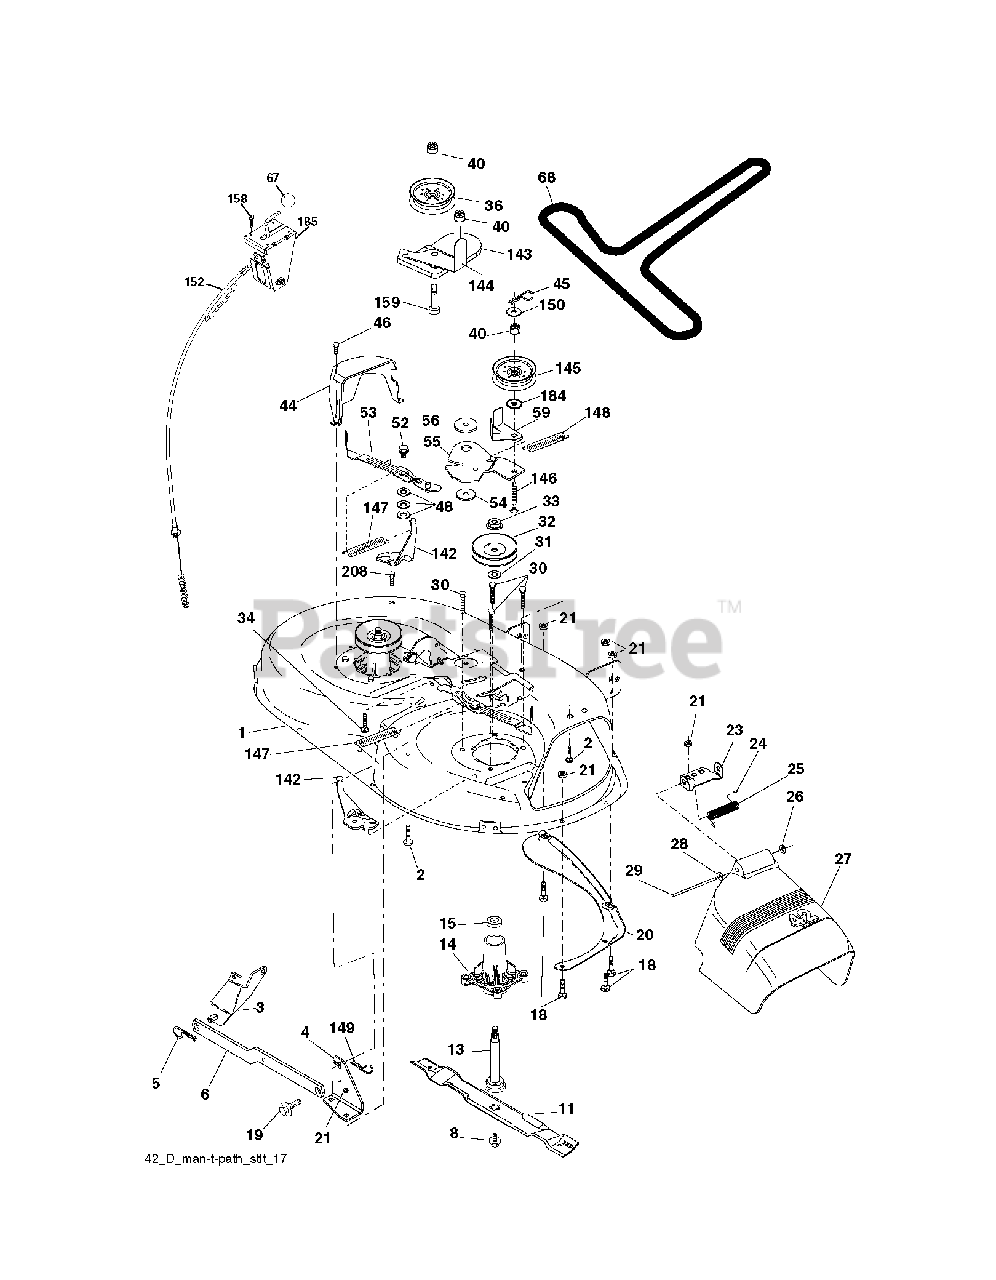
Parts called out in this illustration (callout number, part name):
2	BOLT
3	BRKT ASM SWAY BAR
4	BRACKET SWAY BAR 42" DECK
5	RETAINER-SPRNG RB
6	BAR SWAY DECK
8	BOLT.WASHER.ASM.7/16-2
11	42" HI-LIFT BLADE
13	SHAFT.ASM.MDRL.N/GREASE.38
14	HOUSING.MANDREL.4PT.
18	BOLT
19	BOLT SHD 5/16-18
20	BAFFLE.VORTEX
21	LOCKNUT
23	BRKT, DEFL. MOWER
24	CAP-SLEEVE LT
25	SPRING TORSION
26	NUT PUSH M
27	SHIELD DEFLECTOR
28	WASHER
29	ROD.HINGE
30	SCREW, WASHER HEAD
31	WASHER.SPACER.MANDREL
32	PULLEY/MANDREL
33	NUT.FLANGE.LOCK.TOP
34	BOLT.3/8-16X1.50
36	FLAT IDLER PULLEY
40	NUT LOCK FLG 3/8-16 UNC
44	GUARD MANDREL LH BLACK
46	SCREW.1/4-20X5/8
52	BOLT.SHOULDER.5/16-18
53	ARM BRAKE ASSY
55	ARM IDLER 42" MOWER LT/YT
56	SPACER.RETAINER.MOWER
59	GUARD, BELT
67	KNOB T (3/8 HOLE)
68	BELT V SECONDARY
142	ANCHOR SPRING BRAKE MOWER
143	BRACKET, ARM IDLER
144	KEEPER.BELT.42".CLUTCH.CABLE
145	PULLEY
146	BOLT, CARRIAGE IDLER BLACK
147	SPRING EXTENSION
148	IDLER RETURN SPRING
149	SPRING.RETAINER.YELLOW.ZINC
150	WASHER LT
152	Clutch Cable Kit
158	SCREW
159	BOLT
184	WASHER
185	HEAD ASM. CABLE CLUTCH
208	SCREW 3/8-16X1/2
